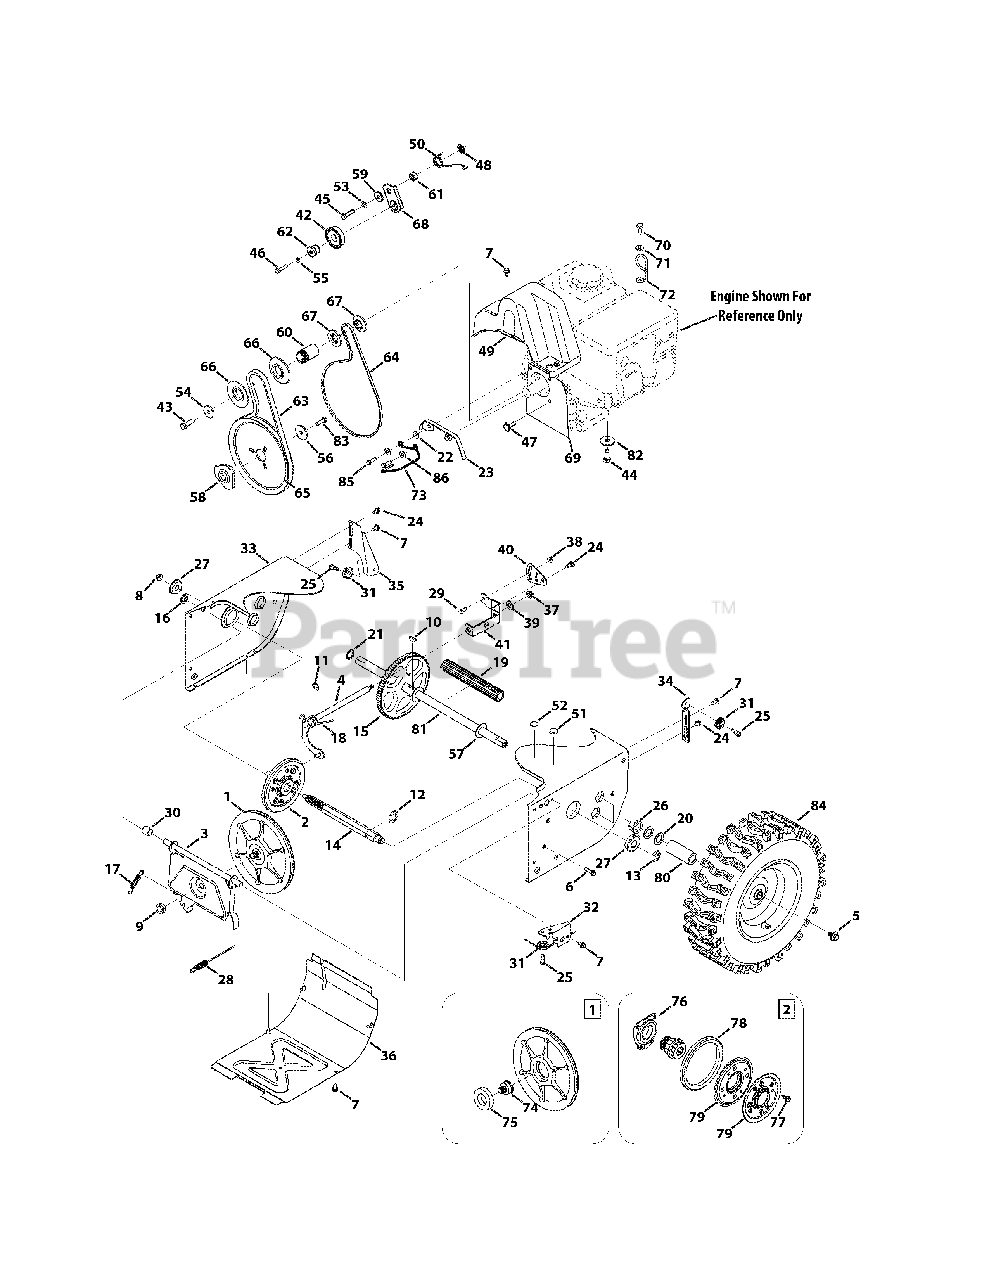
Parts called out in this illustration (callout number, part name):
1	Disc Assembly, Friction Wheel
2	Friction Wheel Assembly, 5.5 OD
3	Friction Wheel Support Bracket
4	Rod Shift Assembly
5	Screw, 5/16-24 x .750
6	Taptite Screw, 1/4-20 x 1.000
7	Taptite Screw, 1/4-20 x .625
8	Flange Lock Nut, 3/8-16
9	Flange Nut, 5/8-18
10	Hi-pro Key, 3/16 x 3/4 Dia.
12	Retaining E-Ring, .875 Dia.
13	E-Ring, .750 Dia.
14	Hex Shaft, 7-Tooth
15	Gear, 80-Tooth
16	Speed Nut, .500
17	Extension Spring
18	Torsion Spring, .750 x .968
19	Axle Spacer
20	Flat Washer, .793 x 1.24 x .060
21	Flat Washer, .75 x 1.00 x .060
22	Washer, Flat, .330 x .687 x .030
23	Belt Cover
24	Shoulder Screw, .368 x .113, 1/4-20
25	Shoulder Screw, 1/4-28, .340 x .355
26	Hex Flange Bearing
27	Ball Bearing, 17 x 40 x 12
28	Wheel Clutch Cable, 44.955"
29	Hex Head Screw, 1/4-20 x .620
30	Spacer, .508 ID x .75 OD x .68
31	Cable Roller
32	Auger Cable Front Guide Bracket
33	Frame
34	Auger Cable Guide Bracket
35	Drive Cable Guide Bracket
37	Flange Lock Nut, 5/16-18
38	Flange Lock Nut, 1/4-20
39	Washer, Flat, .469 x .875 x .105
40	Speed Selector Pivot Bracket
41	Speed Selector Shift Bracket
42	Idler Pulley Assembly
43	Hex Screw, 3/8-24 x 1.25
44	Sems Screw, 3/8-16 x 1.00
45	Hex Screw, 5/16-24 x 1.25
46	Hex Screw, 1/4-20 x 1.25
47	Shoulder Screw, 5/16-24 x .5
48	Push-on Nut, .25 Dia.
49	Belt Cover, 4-Way
50	Torsion Spring, .850 ID x .333
51	Plug, 3/8 ID
52	Plug, 1/2 ID
53	Lock Washer, 5/16
54	Flat Washer, .45 x 1.5 x .172
55	Washer, Lock, 1/4
56	Flat Washer, .34 x 1.50 x .150
57	Washer, Flat, .760 x 1.49 x .060
58	Adapter Pulley, .75 Dia.
59	Shoulder Spacer, .3175 x .5 x .0975
60	Spacer, .875 ID x 1.185 OD
61	Spacer, .340 x .750 x .330
62	Shoulder Space, .260 x .785 x .538
63	Auger Drive Belt, Standard
64	Wheel Drive Belt, Standard
65	Auger Drive Pulley, 8.1 x .5
66	Pulley Half, 2.600 OD
67	Pulley Half, 3/8 x 1.716 OD
68	Wheel Drive Idler Bracket
69	Cover Plate, Standard
70	Hex Head Screw, 1.25 x 20
71	Washer, Flat, .330 x .630 x .0635
72	Cable Guide
74	Friction Disc Bearing Pin
75	Ball Bearing, 30 x 55 x 13
76	Bearing Assembly
77	Taptite Screw, 5/16-18 x .750
78	Friction Wheel Rubber
79	Friction Wheel Plate
80	Spacer, 1.25 x .75 x 3.0
81	Axle, .75 x 22
82	Washer, Flat, .38 x 1.38 x .125
83	Hex Head Screw, 5/16-24 x .875
84	X-Trac Wheel, 13 x 4 x 6, LH
84	X-Trac Wheel, 13 x 4 x 6, RH
85	Hex Head Screw, 5/16-24 x 1.00
86	Washer, Flat, .349 x .879
